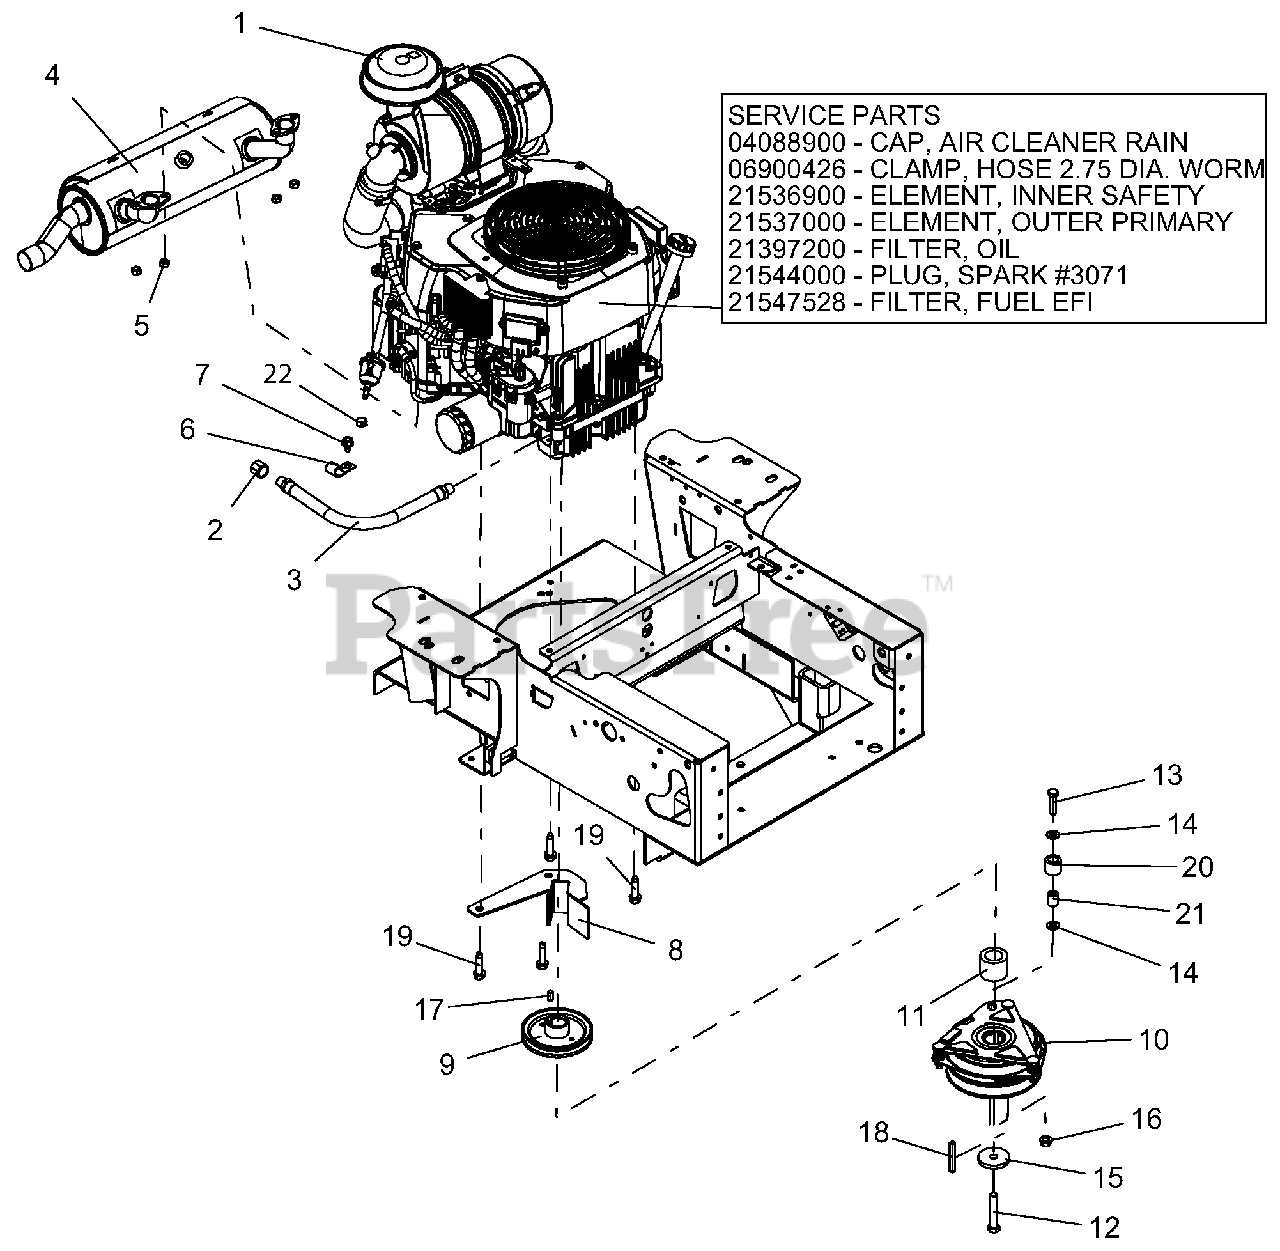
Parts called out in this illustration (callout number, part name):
1	ENGINE, KOHLER EFI ECV730
2	PIPE, CAP 3/8 NPT FEMALE
3	HOSE, HYD .38-11-OK M6N0-M6N0
4	MUFFLER, KOHLER EFI
5	NUT-LK-TOP M8-1.25 YWZC
7	SCR-TAP .38-16X.50 HWH TR YWZ
8	WMT, 100I CLUTCH STOP - BLK
9	PULLEY, 4.50 OD X 1.127 ENGINE-BLACK
10	CLUTCH, OGURA GT2.5-FE02
11	SPACER, 1.125 X 1.75 X 1.40
12	BLT-HEX .44-20X2.50 GR5 EP80 YWZC
13	BLT-HEX .38-16X1.50 GR5 YWZC
14	WSHR-FL-STL.406X.812X.065 YWZ
15	WSHR-FL-STL .469X2.00X.25 YWZC
16	NUT, LK-TOP-FLG .38-16 YWZC
17	KEY-SQ .250X.250X.625
18	KEY, .25X.25X2.25
19	SCR-TAP .38-16X1.50 HWH TR YZ
20	BUMPER, RUBBER .62 X 1.0 X .88 LG
21	BUSHING, SLV .407X.625X.813
22	CLAMP, FUEL LINE
